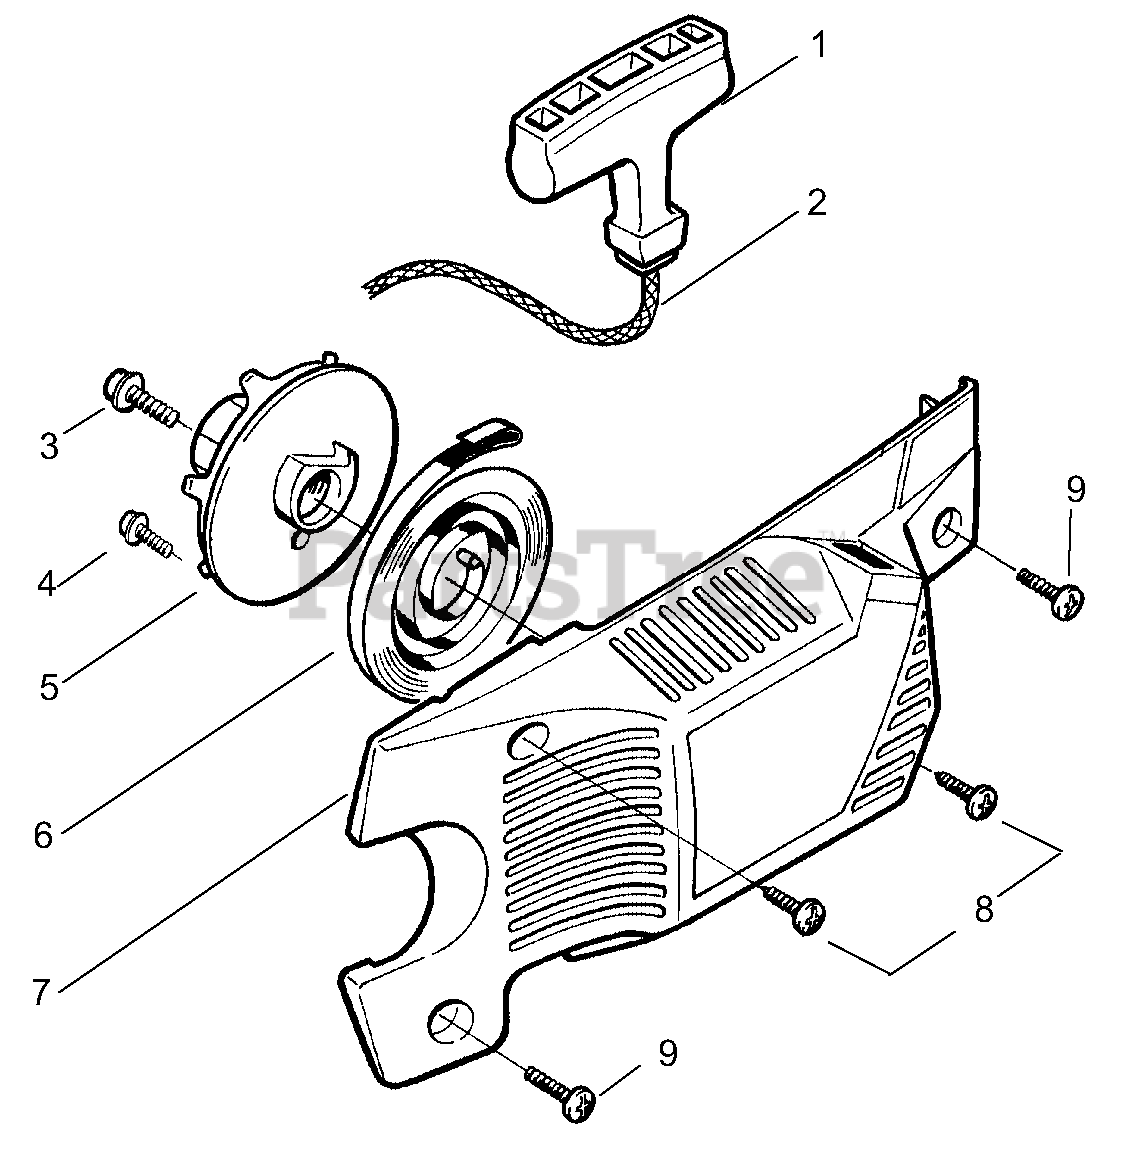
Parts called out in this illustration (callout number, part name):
1	Handle-Starter
5	Kit-Starter Pulley
6	Spring-Recoil
7	Assy-Fan Housing
